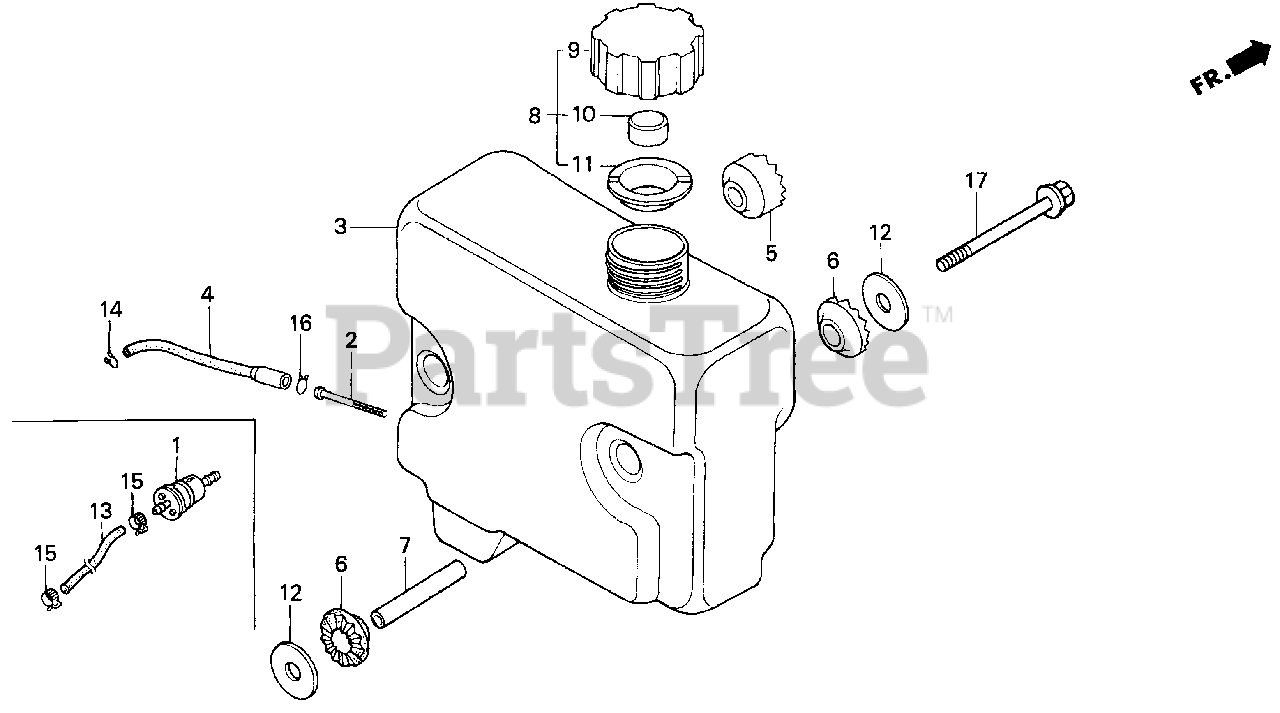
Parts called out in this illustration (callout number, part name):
1	FILTER, FUEL
13	BULK HOSE, FUEL (4.5X3000) (Honda Code 2380558). (4.5X360)
15	CLIP, TUBE (D8.5)
